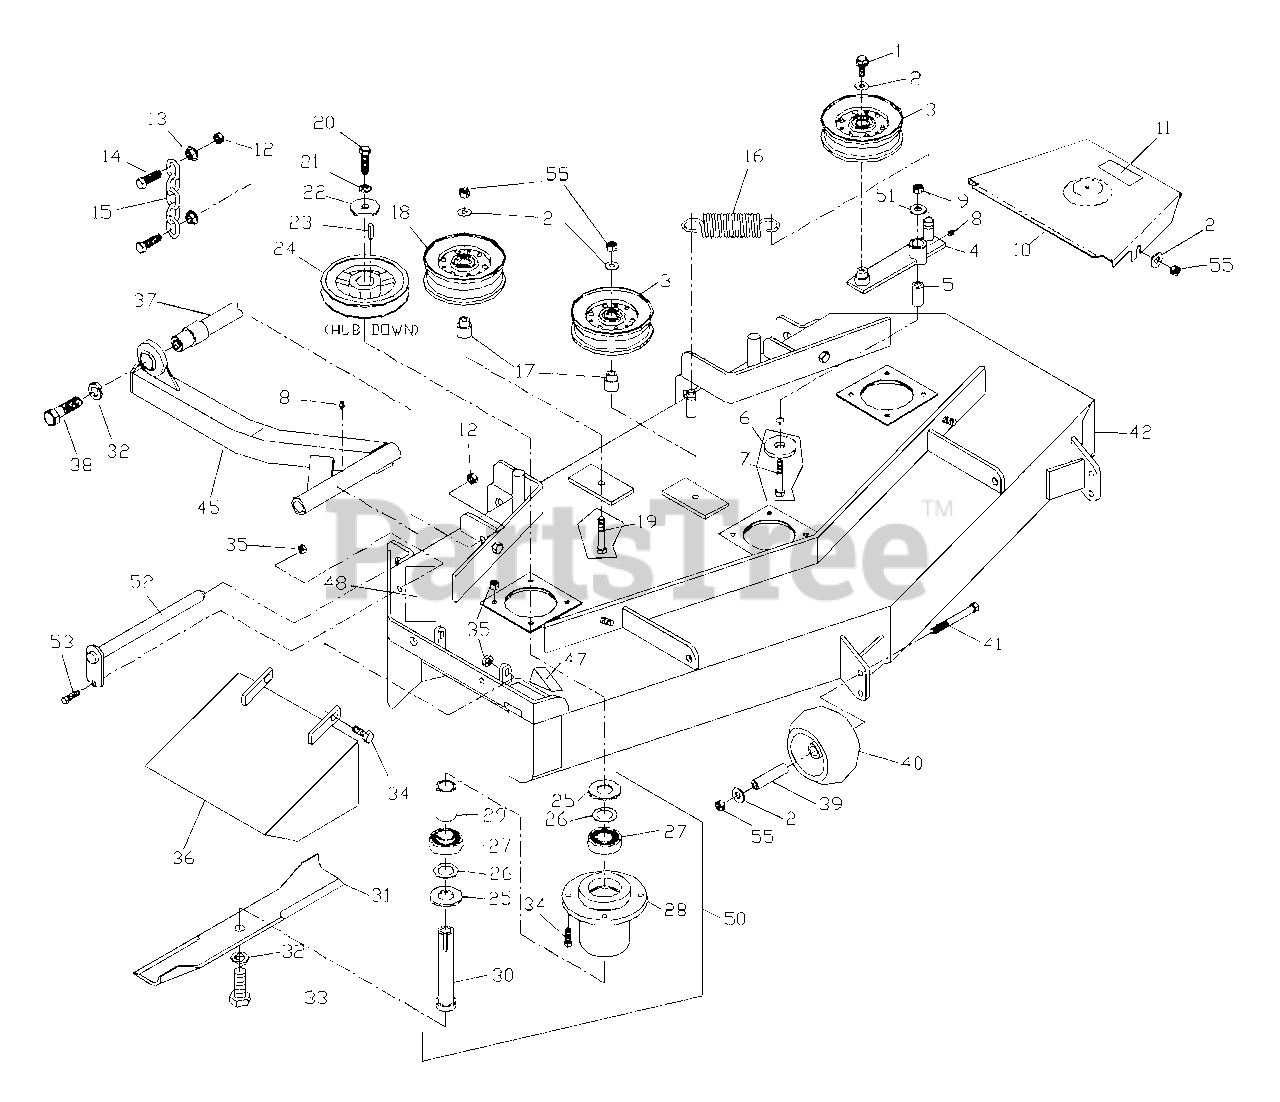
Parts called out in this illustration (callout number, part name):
1	HCS 3/8C X 1 SERRATED HEAD
2	WASHER 3/8 FLAT
3	IDLER PULLEY
5	PIVOT BUSHING
6	SUPPORT WASHER
7	HCS 1/2C X 3 1/4
8	ZERK
9	NUT 1/2C NYLOC
10	BELTSHIELD
11	DECAL, NO STEP
12	NUT 7/16C CENTERLOCK
13	7/16C WHIZ NUT
14	HCS 7/16C X 1 1/2
15	LIFT CHAIN
17	IDLER BUSHING
18	IDLER PULLEY (TALL)
19	HCS 3/8C X 2 1/2
20	HCS 7/16F X 1 1/2
21	LOCKWASHER 7/16
22	CRANKSHAFT WASHER
23	KEY 1/4 SQ. X 1 1/8
25	MACHINE BUSHING 10 GA.
26	MACHINE BUSHING 18 GA.
27	BEARING
31	16 1/4" BLADE
32	LOCKWASHER 5/8
33	HCS 5/8F X 1 1/4
34	HCS 5/16C X 1
35	NUT 5/16C CENTERLOCK
36	DEFLECTOR CHUTE
37	STRUT MOUNT WLDMT
38	HCS 5/8C X 2 GR.5
40	ANTI-SCALP ROLLER
41	HCS 3/8C X 3 1/2
42	DECK W/DECALS
45	STRUT - RT
47	DECAL, CPSC
48	DECAL, DANGER
50	COMPLETE HOUSING
51	WASHER 1/2 FLAT
53	HCS 5/16C X 3/4
55	NUT 3/8C CENTERLOCK
